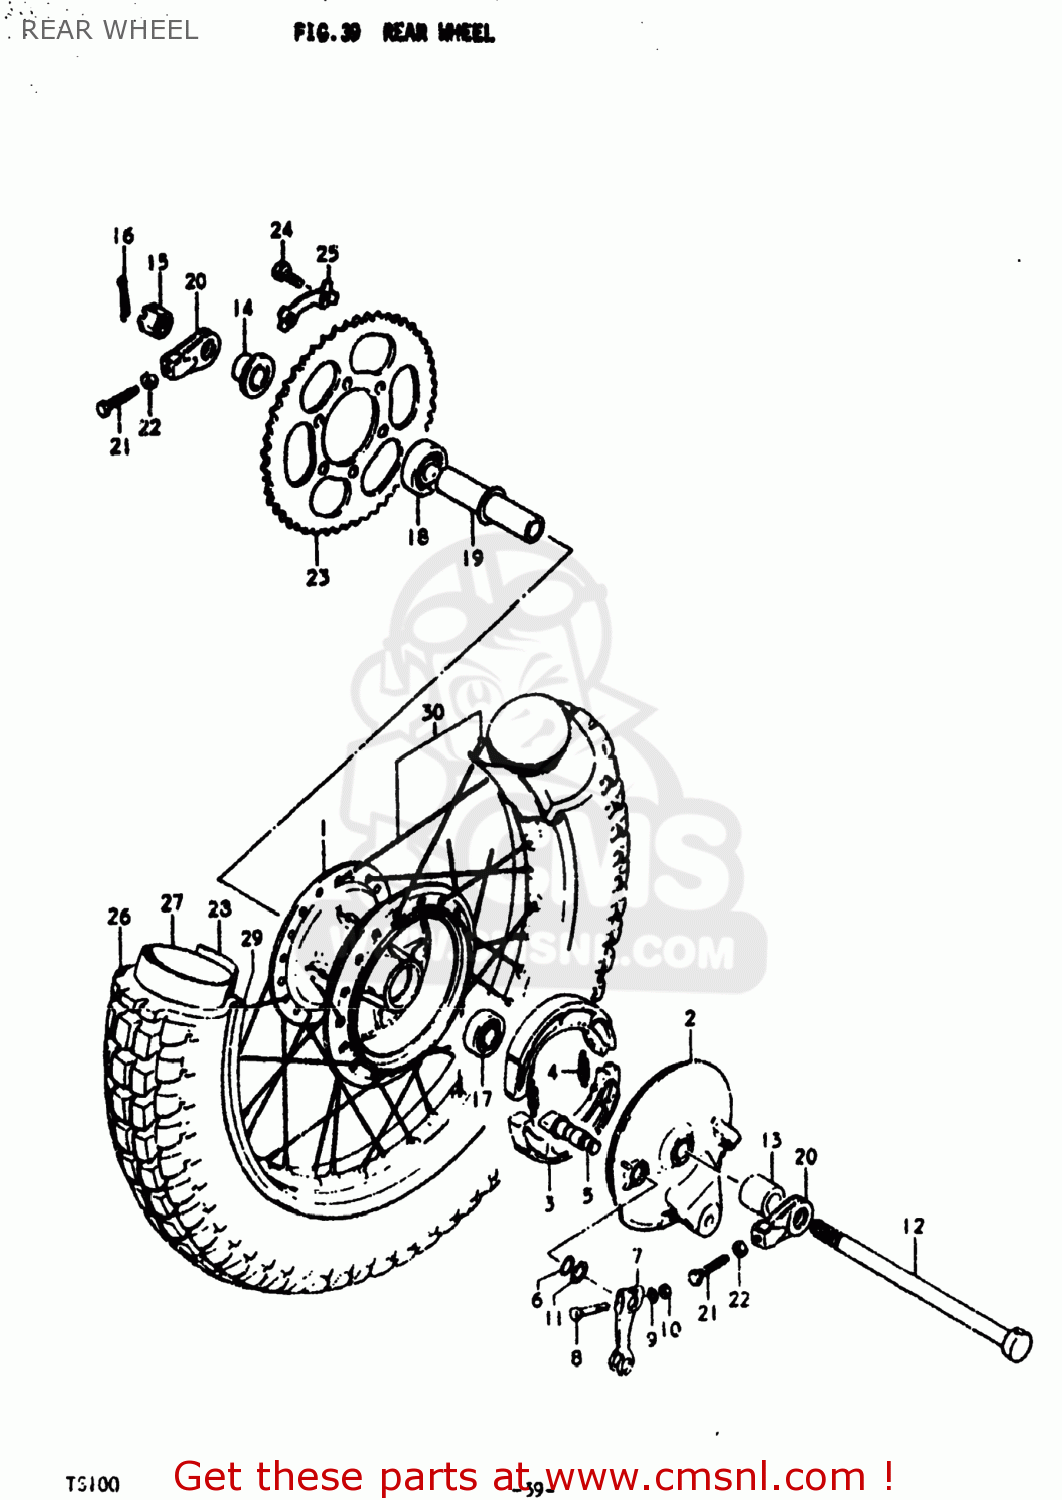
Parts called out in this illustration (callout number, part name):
1	HUB,REAR WHEEL
2	PANEL,RR BRAKE ANCHOR
3	SHOE,BRAKE
4	SPRING(L:34)
5	CAM,FRONT BRAKE
6	O-RING (D:2.4 ID:13.8)
7	LEVER,RR BRAKE CAM
8	BOLT(6X33)
9	WASHER
10	NUT
11	WASHER (14.5X22X1.6)
12	AXLE,REAR
13	SPACER(15.2X22X26)
14	SPACER,RR AXLE,L
15	NUT
16	COTTER PIN
17	BEARING
18	BEARING
19	SPACER,RR WHEEL HUB BEARING
20	ADJUSTER,CHAIN,R
21	BOLT
22	NUT
23	SPROCKET,RR
24	BOLT(8X30)
25	WASHER
26	TIRE
27	TUBE,INNER
28	PROTECTOR,INNER TUBE
29	RIM,RR WHEEL
